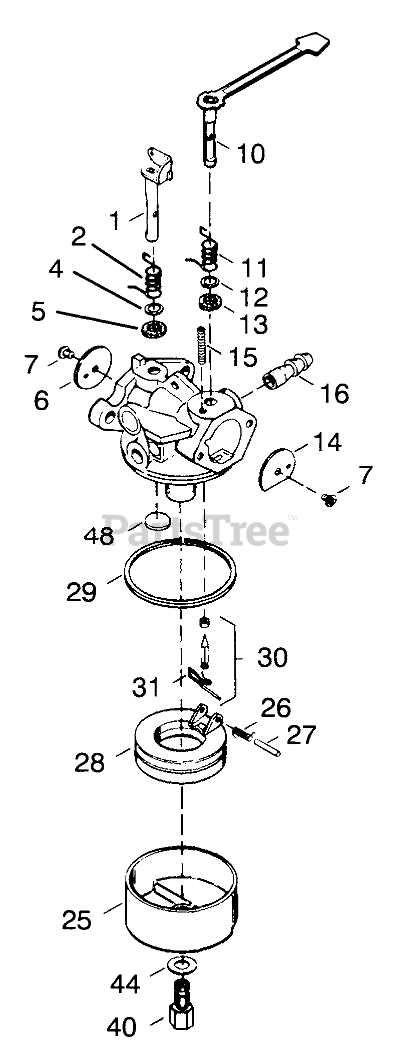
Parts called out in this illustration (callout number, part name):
1	Throttle Shaft & Lever Asm.
2	Spring-Trottle, Return
4	Washer-Seal, Dust
5	Seal-Dust
6	Shutter-Throttle
7	Screw-Shutter
10	Choke Shaft and Lever ASM
14	Shutter-choke
15	Spring-Positioning, Choke
16	Fitting-Fuel
25	Bowl Float
26	Spring-Float, Dampening
27	Shaft-Float
28	Float
29	O Ring-Bowl, Float
30	Inlet Needle, Seat & Clip (Incl. ref. #31)
31	Clip-Spring
40	Nut-Float Bowl
44	Gasket-Bowl
48	Plug-Welch, Atmospheric Vent
